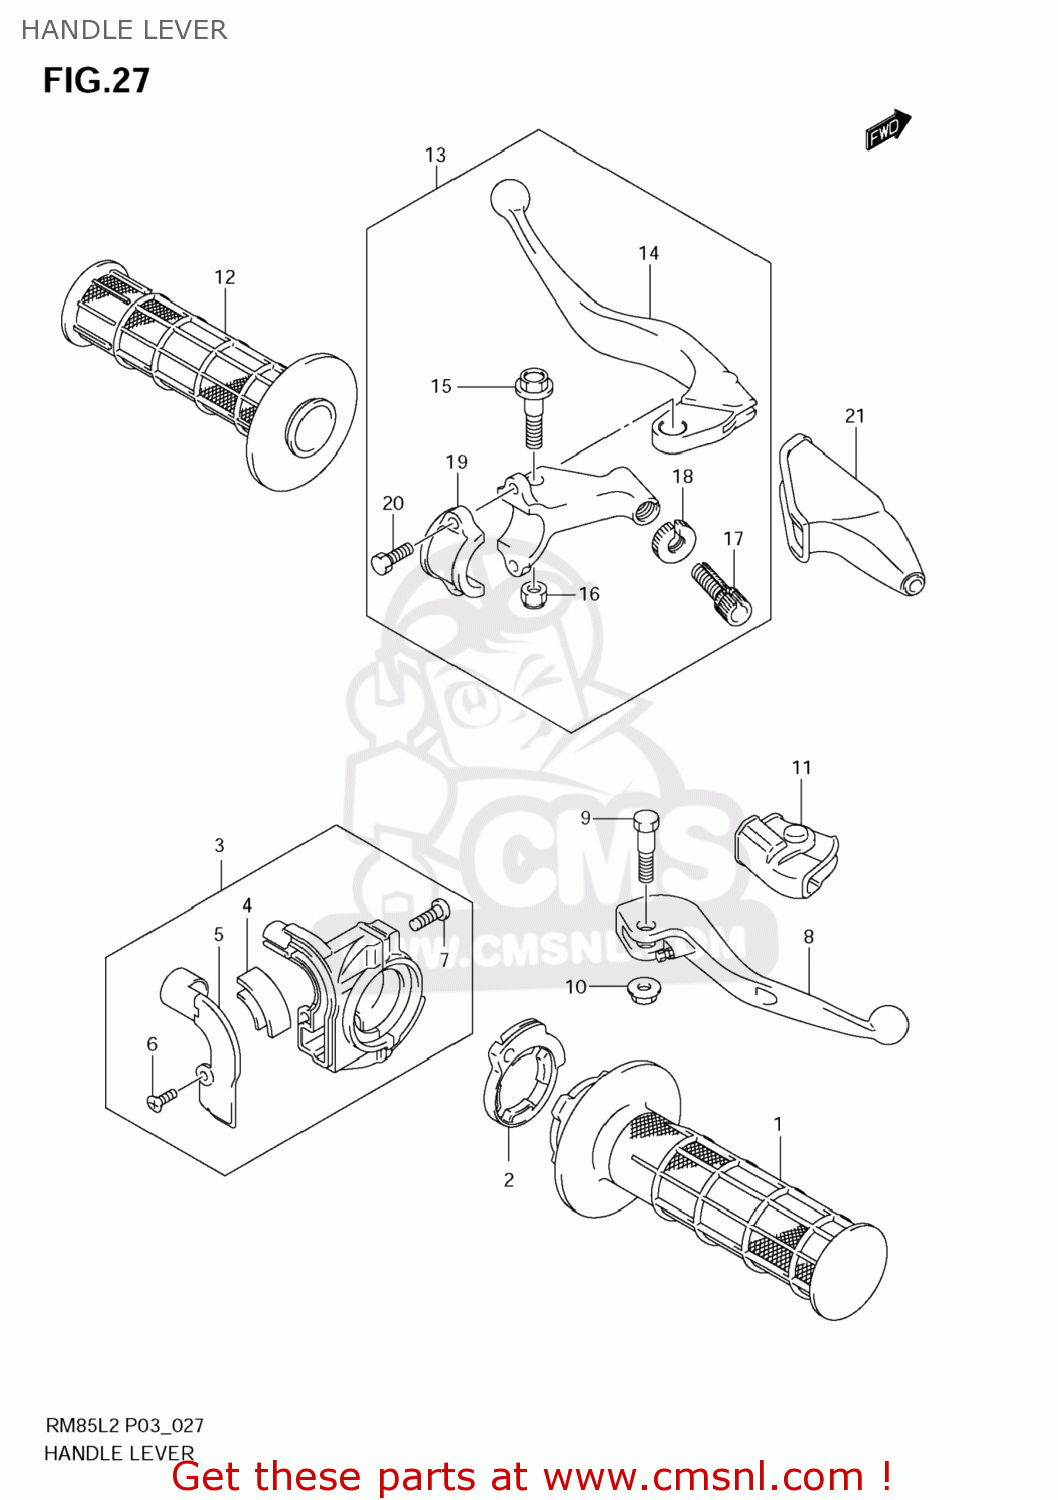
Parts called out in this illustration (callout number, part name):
1	GRIP,THROTTLE
2	ROTER,THROTTLE
3	CASE ASSY,THROTTLE
4	GUIDE
5	COVER
6	SCREW
7	SCREW
8	LEVER ASSY,BRAKE
9	BOLT,BRAKE LEVER
10	NUT
11	COVER,BRAKE LEVER
12	GRIP,L
13	LEVER ASSY,CLUTCH
14	LEVER,CLUTCH
15	BOLT,LEVER
16	NUT
17	ADJUSTER,WIRE
18	NUT,LOCK
19	BRACKET,CLUTCH LEVER HOLDER
20	BOLT
21	COVER,CLUTCH LEVER
